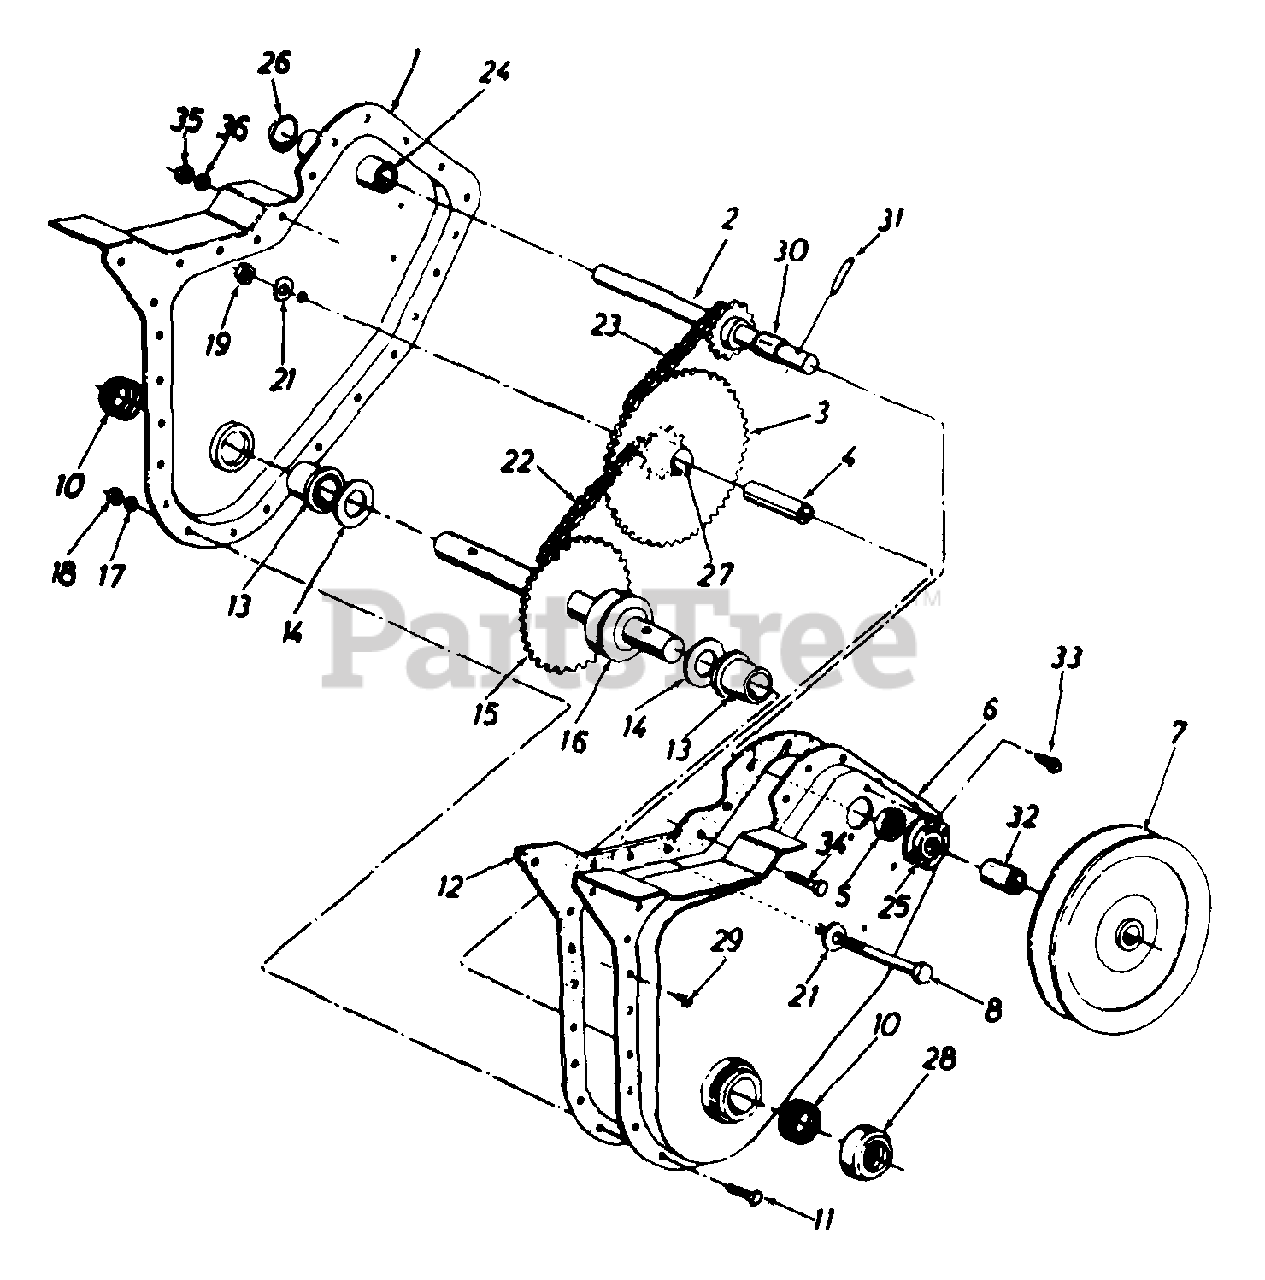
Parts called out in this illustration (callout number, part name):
1	Chain Case Ass'y.- R.H.
2	Input Shaft Ass'y.
3	Hub and Sprocket Ass'y.
4	Bearing Inner Race
5	Ball Bearing
8	Hex Bolt 3/8-24 x 2.5"
10	Seals
11	Hex Bolt 1/4-26 x .625"
12	Gasket
13	Flange Brg..879" I.D.
14	Fl-Wash..88" I.D. x 1.5"
15	Tine Shaft Ass'y.
16	Spacer 7/8" I.D.
17	L-Wash. 1/4" I.D."
18	Hex Nut 1/4-28 Thd.
19	Hex Ins. L-Nut 3/8-24 Thd.
21	Bell-Wash..406" I.D.
22	Chain #420 1/2" Pitch 38 Links
23	Chain #35 .375" Pitch 50 Links
24	Bearing .62" I.D. x .813"
25	Bearing Housing
26	Expansion Plug 13/16" Dia.
27	Bearing
28	Dust Capful
29	Hex Wash. Hd. Self-Tap Scr. 1/4-20 x .50" Lg.
30	Spacer.63" I.D. x.77" 0 D. x.38" Lg.
31	Spring Pin Spiral 1/4" Dia. x 1-1/2" Lg.
32	Spacer .647 x 1.25"
33	Hex Wash. Hd. Self-7ap Scr. 1/4-20 x .38" Lg.
34	Hex Bolt 5/16-18 x .75" Lg.
35	Hex Nut 5/16-18 Thd."
36	L-Wash. 5/16" I.D.
